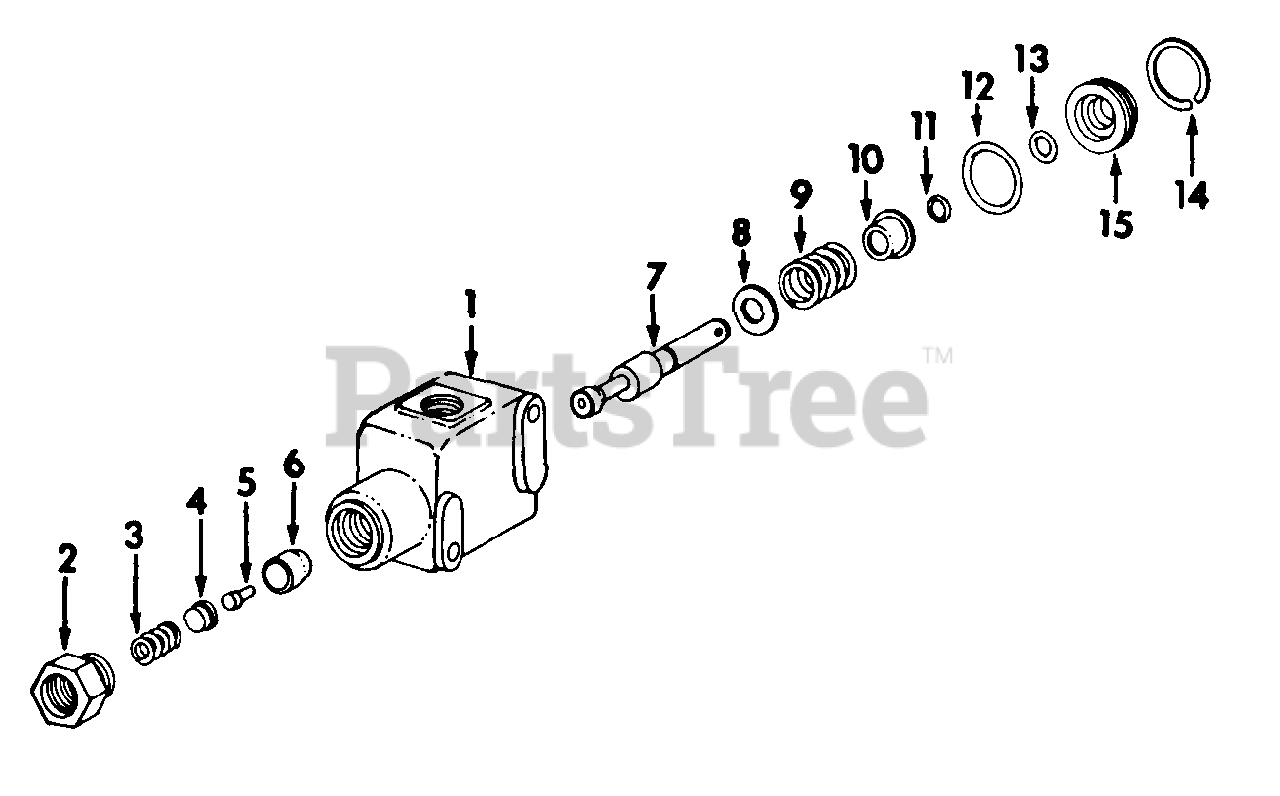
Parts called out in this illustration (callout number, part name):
1	BODY ASSY, POPPET VALVE
2	PLUG, ADAPTOR PORT
3	SPRING
6	POPPET
7	SPOOL
10	WASHER, DEEP
11	SNAP RING
12	O-RING
13	O-RING
15	RING, RETAINING
